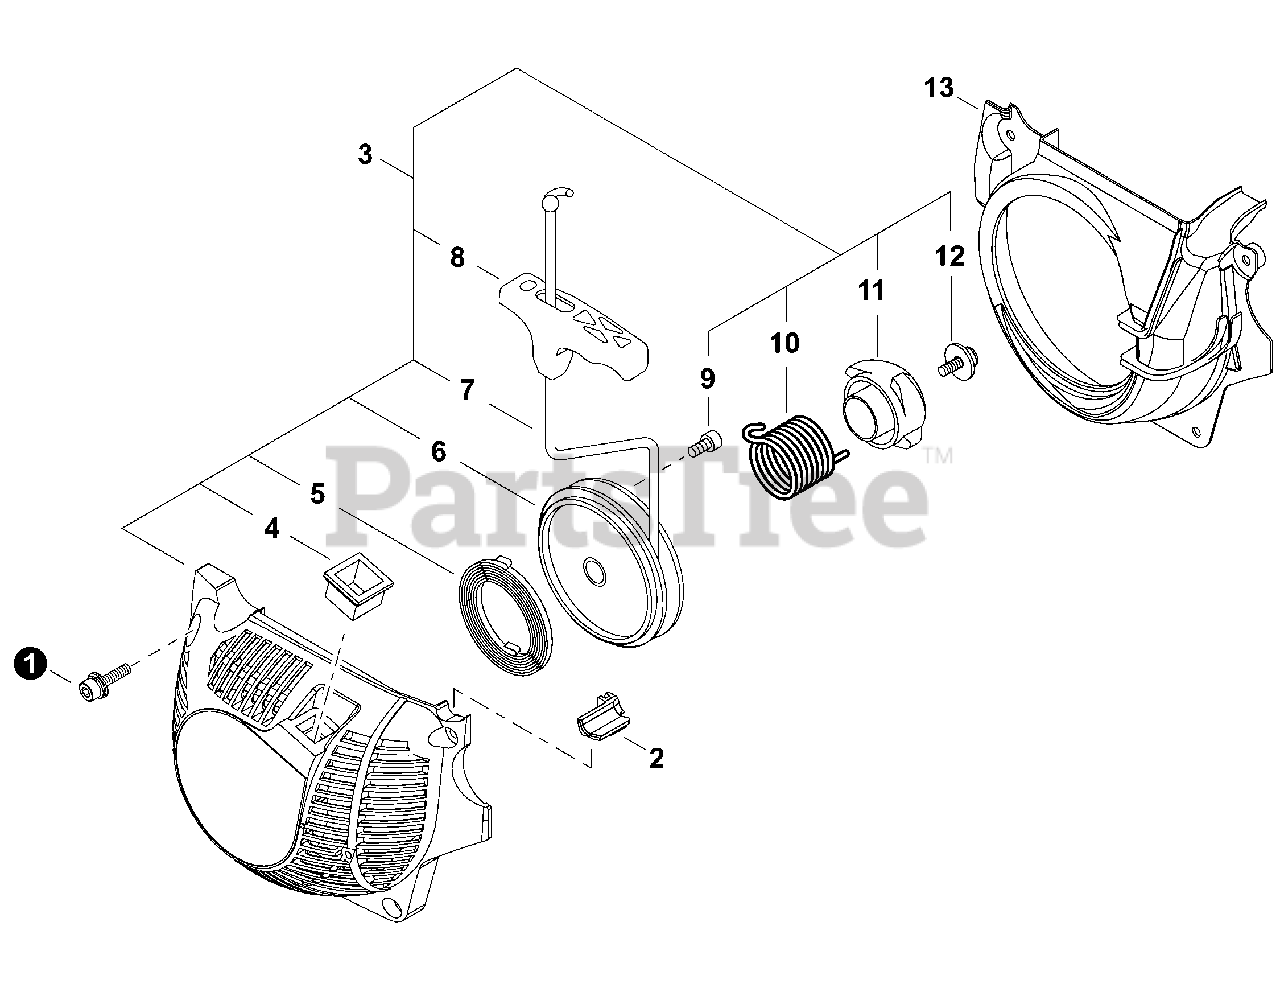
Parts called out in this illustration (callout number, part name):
1	BOLT M4×16
2	GROMMET, NEEDLE
3	STARTER ASSY, RECOIL
4	GUIDE, ROPE
5	SPRING, RECOIL
6	REEL, ROPE
7	ROPE, STARTER 3.8×750
8	GRIP, STARTER
9	BOLT 4×10
10	SPRING, TORSION
11	PAWL CATCHER
12	SCREW 5
13	COVER, FAN
